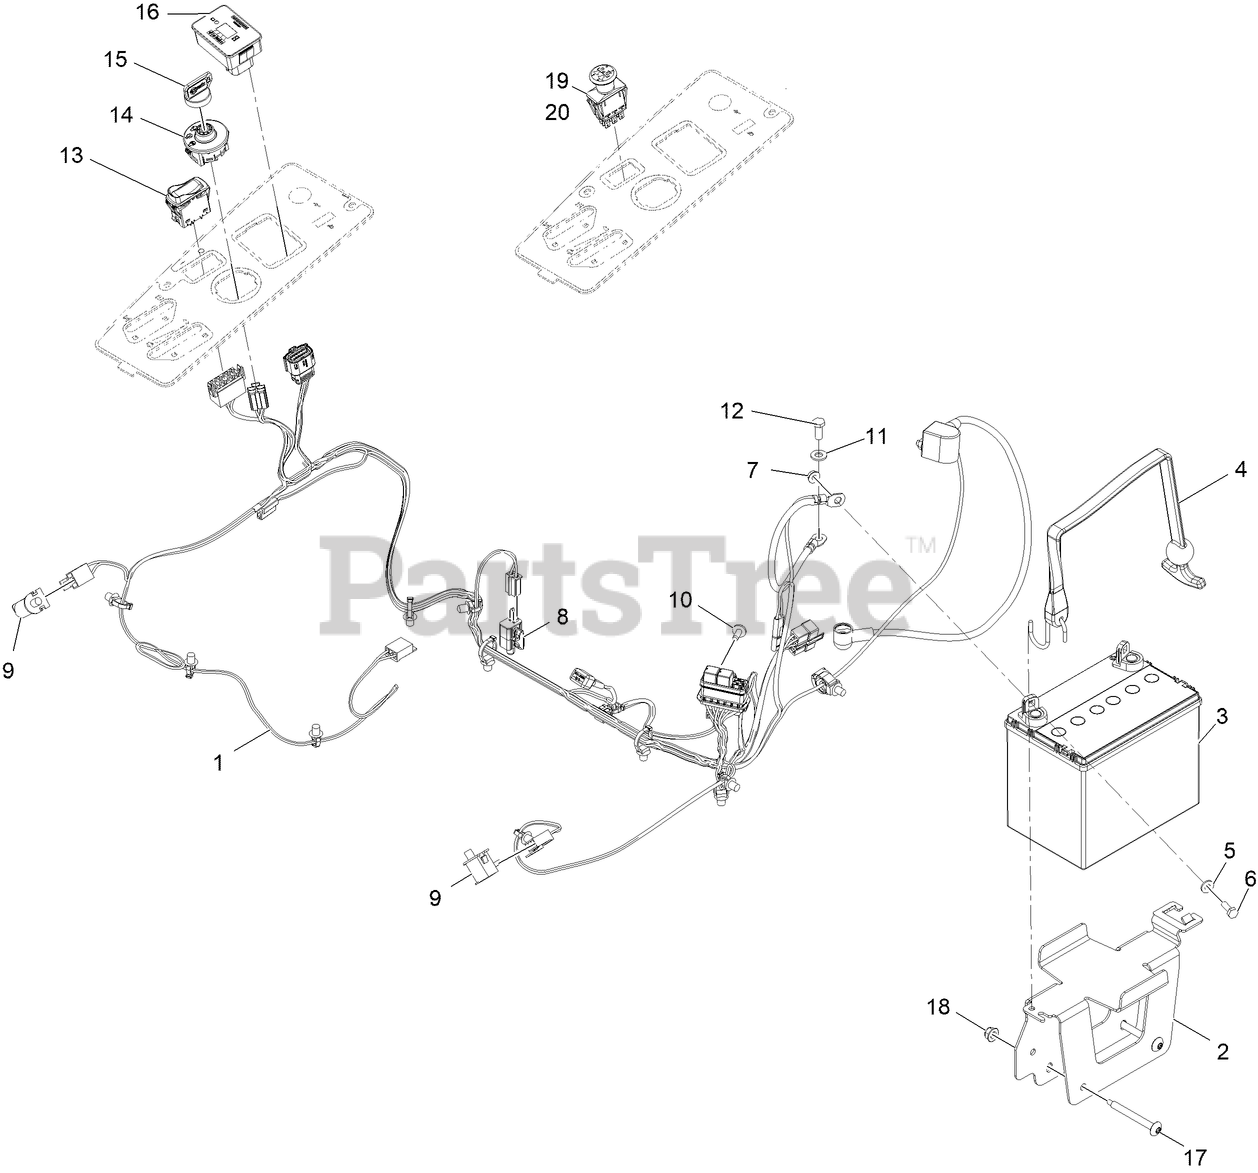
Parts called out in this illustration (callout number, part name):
1	Harness-Wire
2	TRAY-BATTERY
3	Battery
4	STRAP, BUNGEE
5	WASHER-FLAT
6	SCREW-HH
9	SWITCH-BAIL
10	SCREW-TORX
11	WASHER-PLAIN
12	SCREW-HH
13	SWITCH-ROCKER, ON-NONE-ON
14	SWITCH-IGNITION
15	KEYS-IGNITION (SPARE PAIR
15	KEY-IGNITION
16	MODULE ASM
17	SCREW-TORX
18	NUT-HF, NI
19	SWITCH-PTO
